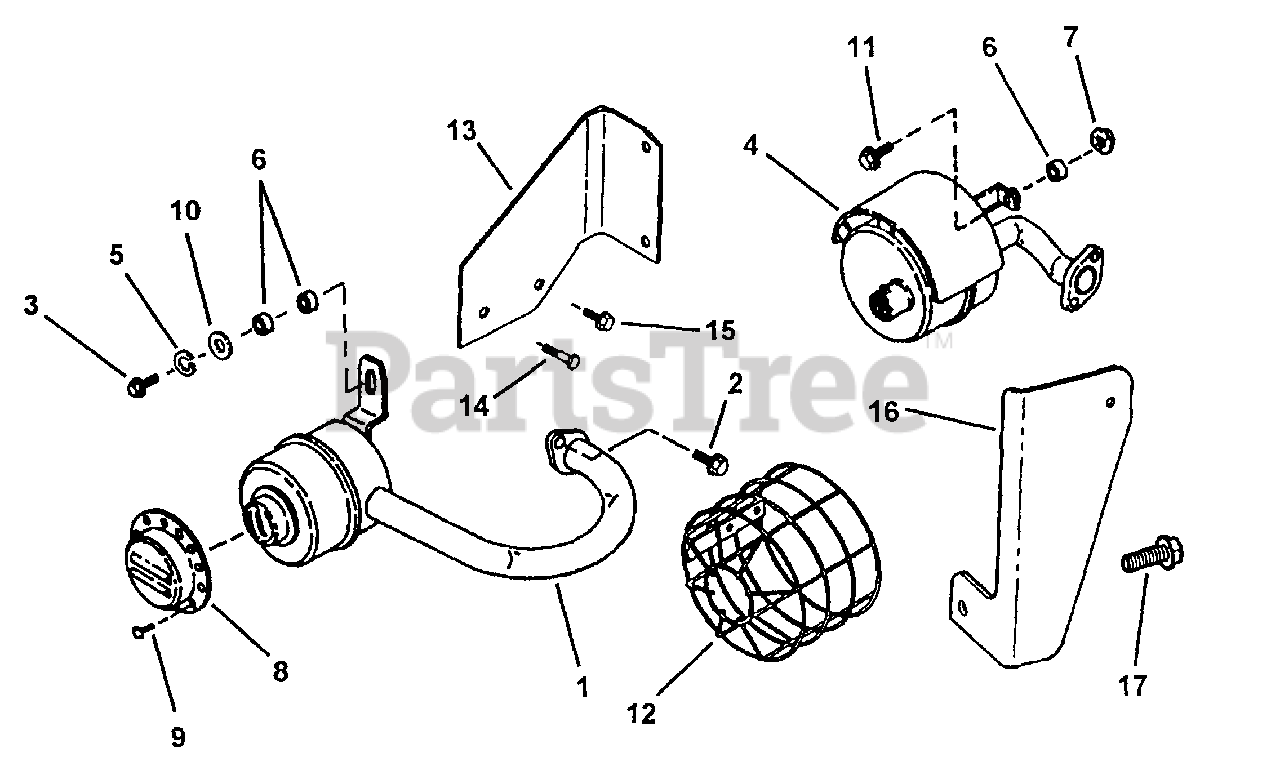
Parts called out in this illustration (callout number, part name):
1	MUFFLER (B&S 9-13 HP)
2	SCREW, 5/16-18 x 3/4" Hex Head Cap, Grade 2
3	SCREW, 1/4-20x1-1/4" Hex Head Cap
4	MUFFLER (Kohler 14/15 HP)
5	WASHER, 1/4" Split Lock
6	SPACER
7	NUT, 1/4-20 Hex Flange Lock
8	DEFLECTOR, Heat
9	SCREW #8-18 x 3/8" Type AB Modified
10	WASHER, 1/4" Flat
11	SCREW, 1/4-20 x 314" Hex Head Cap, Grade 5
12	GUARD, Muffler (Kohler)
13	BRACKET, Muffler Guard (Kohler)
14	SCREW, 1/4-20 x 1" Hex Head Cap, Grade 5
15	SCREW, 1/4-20 x 5/8" Hex Head Self-Tap
16	BRACKET, Heat Shield (Briggs)
17	SCREW, 5/16-18 x 1" Hex Washer Self-Tap
